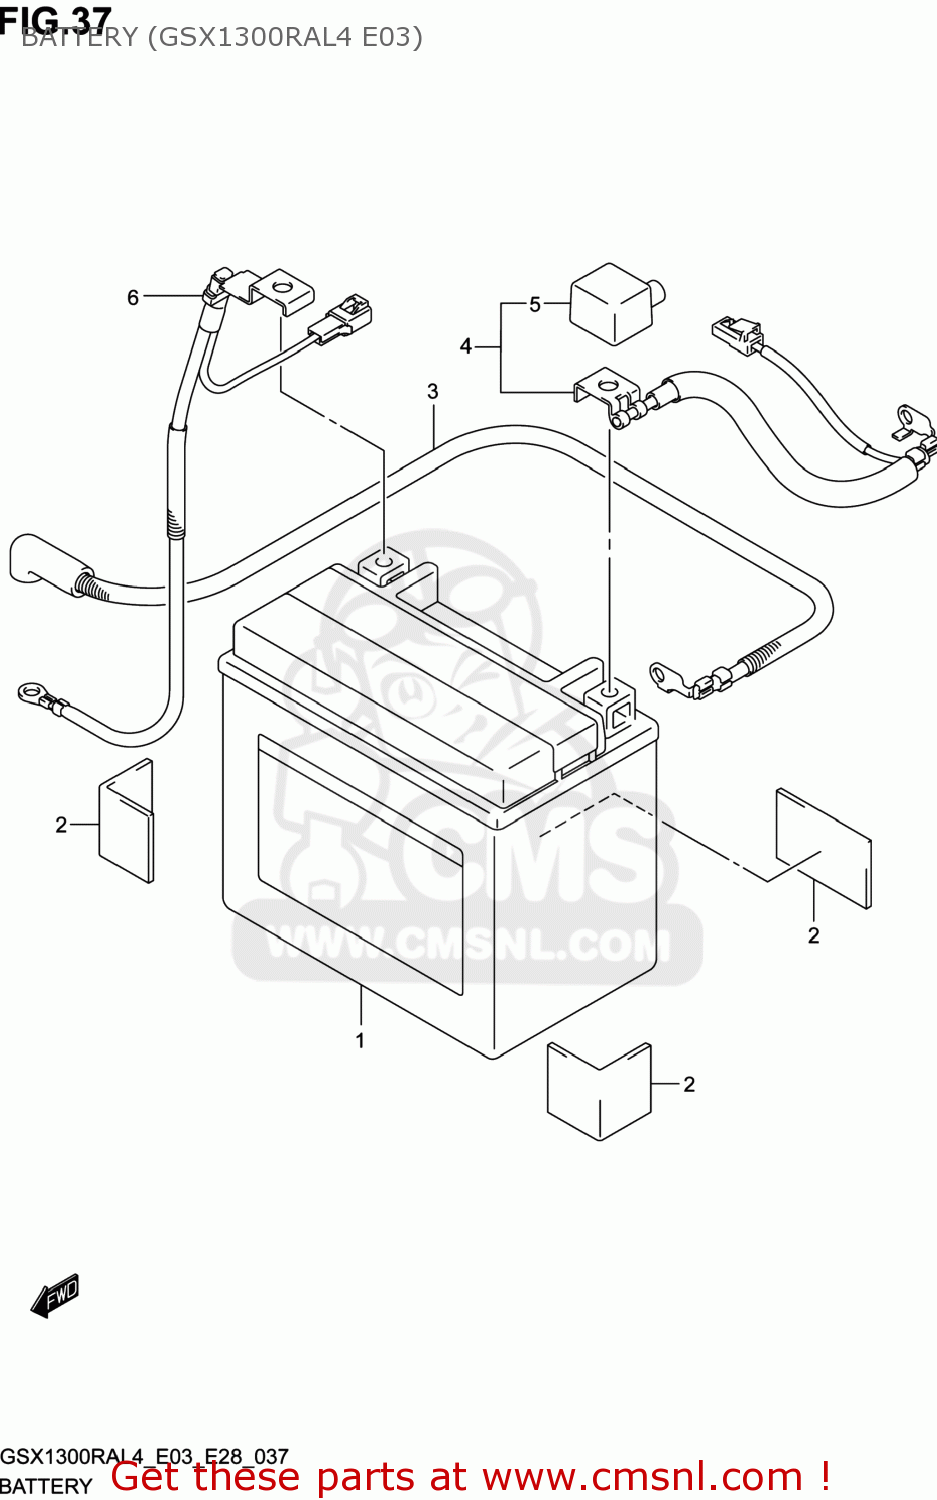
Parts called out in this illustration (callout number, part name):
1	BATTERY ASSY(YTX12-BS,12V10AH)
2	CUSHION(30X50X3)
3	WIRE,STARTER MOTOR LEAD
4	WIRE,BATTERY PLUS LEAD
5	CAP,BATTERY PLUS
6	WIRE,BATTERY MINUS LEAD
